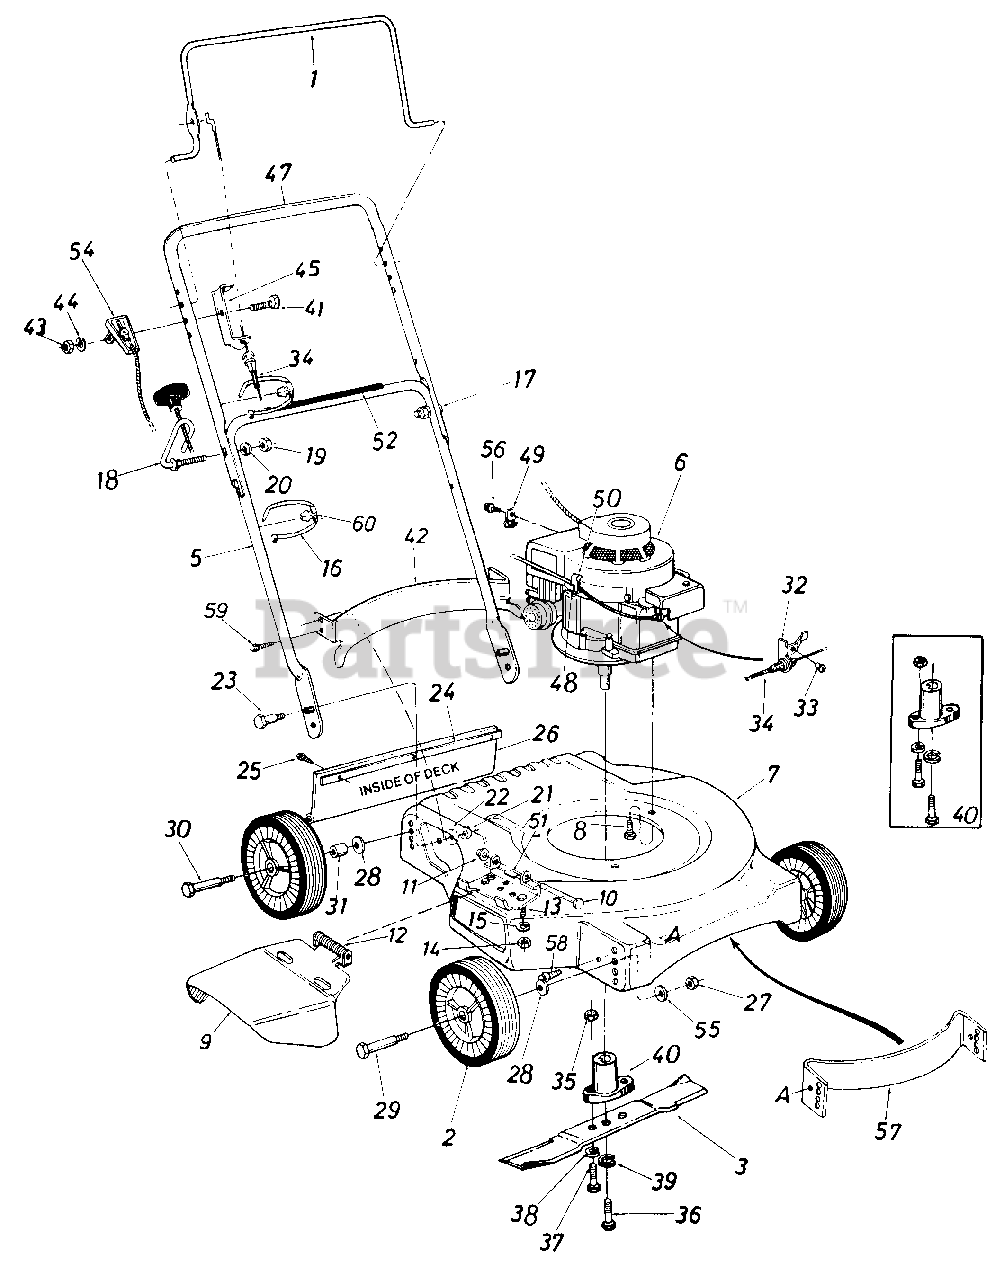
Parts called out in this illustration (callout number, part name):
1	Control Handle
2	Plastic Wheel Ass'y.
5	Lower Handle
6	Engine
8	Hex Wash Hd TT Tap Scr. 3/8-16 x 1.00" Lg.
9	Chute Deflector Ass'y.
11	Cap Speed Nut 1/4" Rod
12	Torsion Spring
13	Hex Bolt 1/4-20 X .50" Lg.*
14	Hex Nut 1/4-20 Thd.*
15	L-Wash. 1/4" I.D.*
17	Curved Carriage Bolt 5/16-18 x 1.38" Lg.
18	Rope Guide Bolt
19	Hex Nut 5/16-18 Thd.*
20	L-Wash. 5/16" I.D.*
21	Hex Ins. L-Nut 5/16-18 Thd.
22	Bell-Wash. .345" I.D. x .88" O.D.
23	Shld. Bolt .437" Dia. x .180" Lg.
24	Retainer Strip
25	Hex Wash. Hd. Self-Tap Scr. 1/4" X .62" Lg.
26	Rear Flap Ass'y.
27	Hex Nut 3/8-16 Thd.*
28	Bell-Wash. .400" I.D. x .88" O.D.
29	Shld. Bolt
30	Shld. Bolt
32	Cable Bracket
33	Pop Rivet .156" Dia. x .379
34	Control Cable 43.0" Lg.
35	Hex Nut 5/16-24 Thd.*
36	Hex Bolt 3/8-24 x 1.00" Lg. (Grade 5)
37	Hex Bolt 5/16-24 x 1.00" Lg. (Grade 5)
38	L-Wash. 5/16" I.D.*
39	L-Wash. 3/8" I.D. Heavy Duty
40	Blade Adapter Kit
41	Hex Bolt 1/4-28 x 1.75" Lg.
42	Rear Bafflet
43	Hex Nut 1/4-28 Thd.
44	L-Wash. 1/4" I.D.
45	Cable Mounting Brkt.
47	Upper Handle
48	Hex B-Tap Scr. #10 x .38" Lg.
49	Casing Clamp
50	Casing Clamp
51	Hinge Plate
52	Instruction Label Handle
54	Throttle Control Ass'y. Comp.
55	Bell-Wash. .39" I.D. x 1.13" O.D.
56	Hex AB-Tap Scr. #8 x .38" Lg.
57	Baffle Optional Parts
58	Hex B-Tap Screw 1/4 x .38" Lg.
59	Hex Tap Screw #10 x .50" Lg.
60	Cable Anchor
